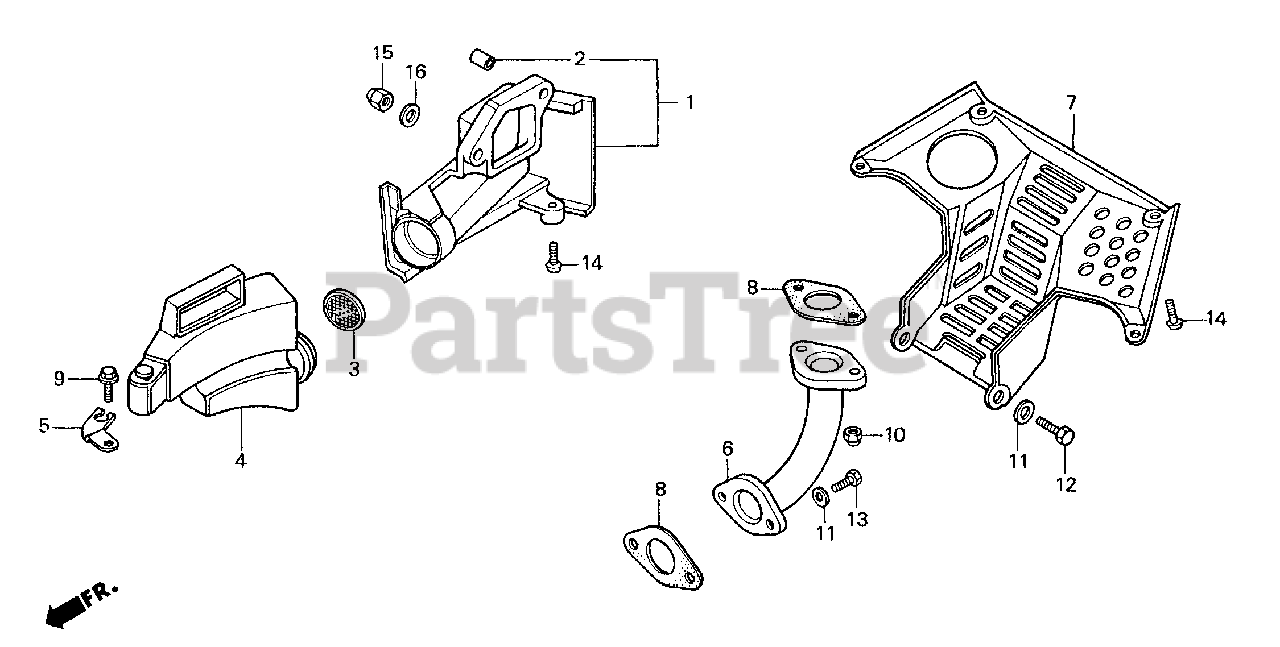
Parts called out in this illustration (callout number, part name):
1	GUIDE, AIR
2	COLLAR, DISTANCE
3	TRAP, FLAME
4	CHAMBER, AIR GUIDE
5	STAY, AIR GUIDE CHAMBER
7	PROTECTOR, EX. PIPE
8	GASKET A, EX. PIPE
9	BOLT, FLANGE (6X18)
10	NUT, CAP (6MM)
11	WASHER, PLAIN (6MM)
12	BOLT, HEX. (6X12)
13	BOLT, HEX. (6X16)
14	SCREW, TAPPING (5X16)
15	NUT, CAP (5MM)
16	WASHER, PLAIN (5MM)
